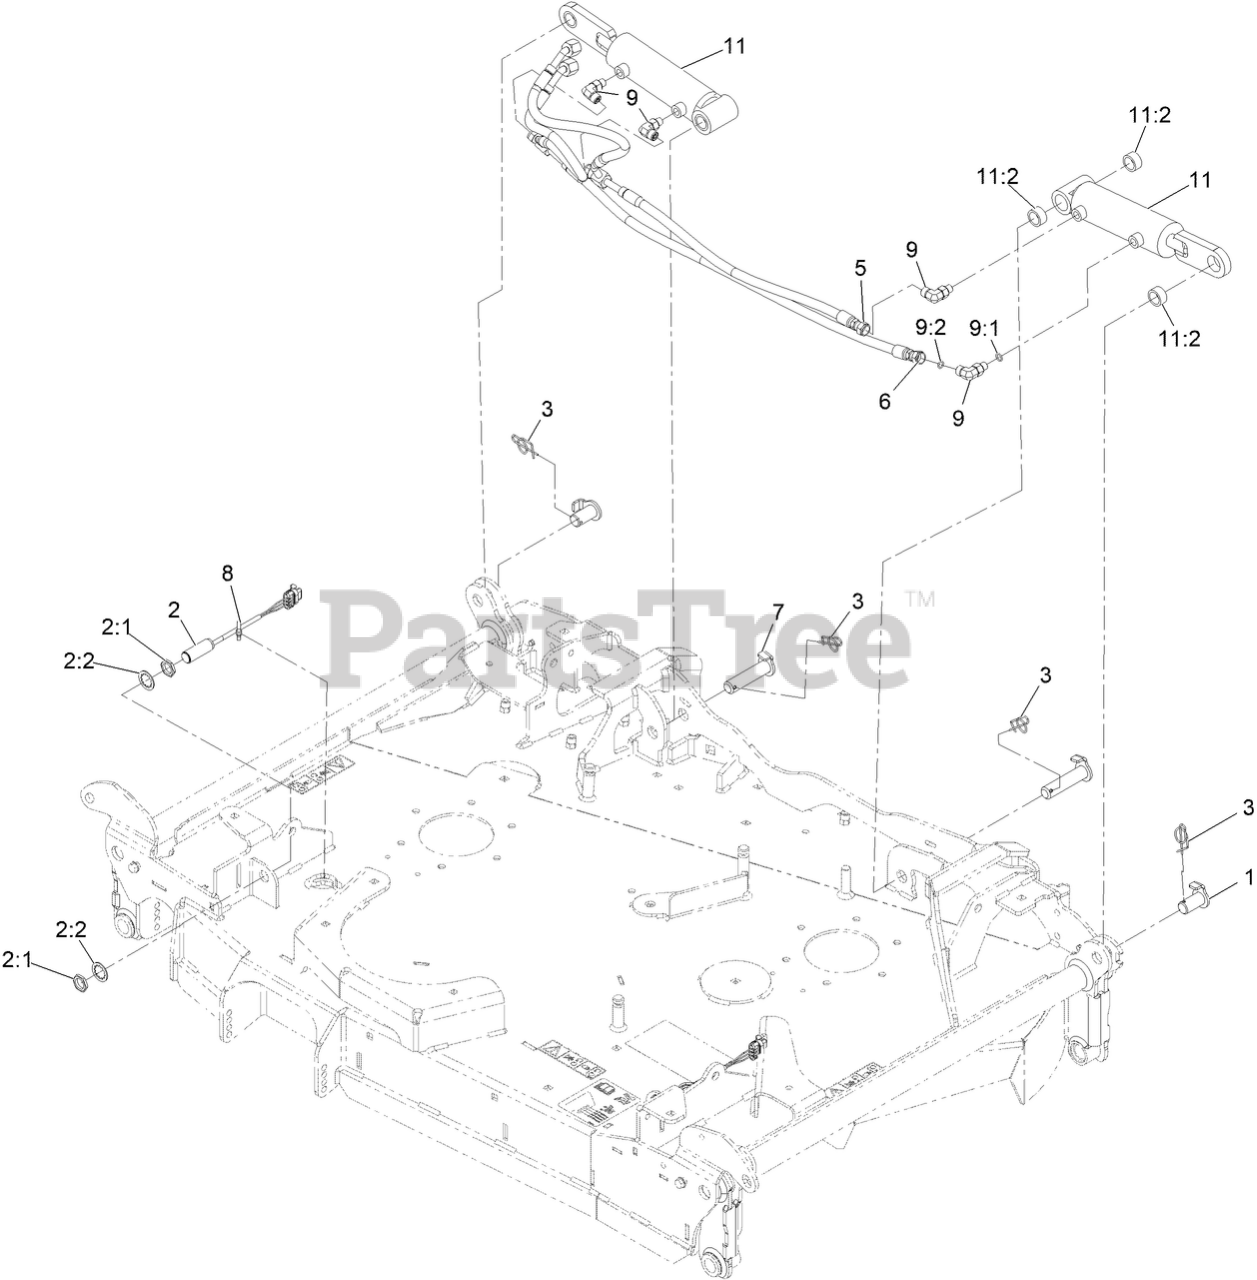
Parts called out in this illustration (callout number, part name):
1	PIN-CYLINDER
2	PROXIMITY SWITCH ASM
2:1	NUT-HEX
2:2	WASHER-LOCK, INTERNAL TOO
3	PIN-LOCKING COTTER
5	HOSE ASM
6	HOSE ASM
7	ASM-CYL PIN BASE
8	TIE-CABLE
9	FITTING-ELBOW, 90 DEG
9:1	O-RING
9:2	O-RING
11	CYL-Deck Fold
11:2	BUSHING-0.75X1.00X0.50 LONG
